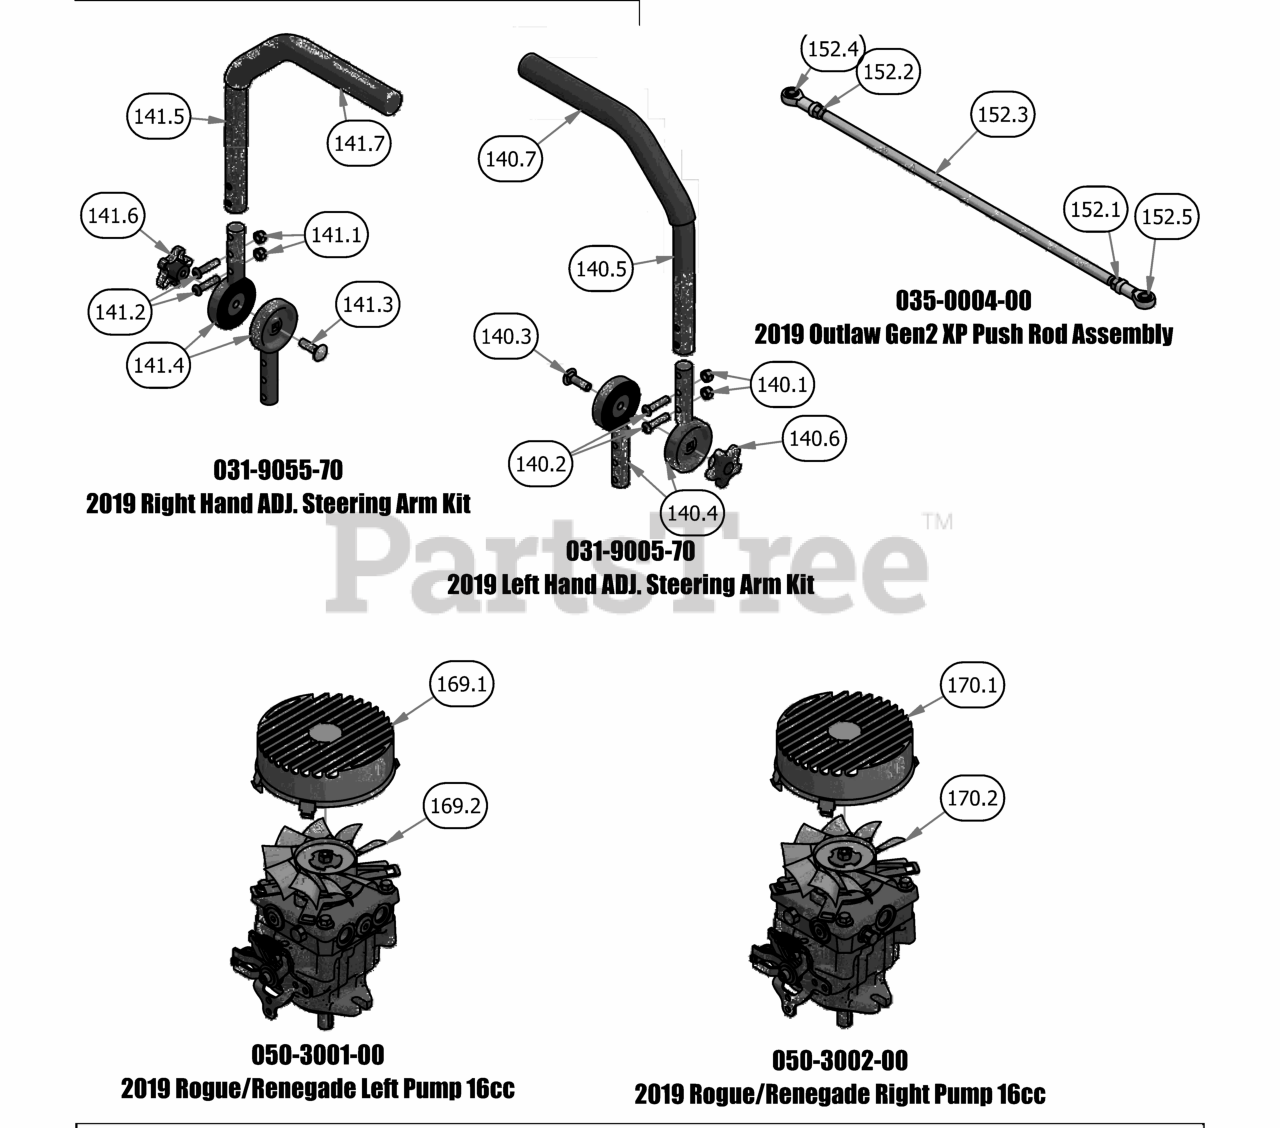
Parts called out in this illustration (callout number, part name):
140.1	5/16-18 Nylock Insert Locknut
140.2	5/16-18 BHCS, TORX DRIVE
140.3	3/8" x 1 1/4" Carriage Bolt
140.4	2019 Steering Arm Adjuster Casting
140.5	2019 Steering Arm Grip
140.6	Black Knob for Adjustable Steering Arm
140.7	Black Steering Arm Grip
141.1	5/16-18 Nylock Insert Locknut
141.2	5/16-18 BHCS, TORX DRIVE
141.3	3/8" x 1 1/4" Carriage Bolt
141.4	2019 Steering Arm Adjuster Casting
141.5	2019 Steering Arm Grip
141.6	Black Knob for Adjustable Steering Arm
141.7	Black Steering Arm Grip
152.1	5/16" RH Fine Threaded Jam Nut
152.2	5/16" LH Fine Threaded Jam Nut
152.3	2019 Outlaw Gen2 Xp Rod
152.4	Spherical Rod End - Outlaw
152.5	Spherical Rod End - Outlaw
169.1	Fan Guard 6" Fits wheel Motor Pumps
169.2	Hydraulic Fan
170.1	Fan Guard 6" Fits wheel Motor Pumps
170.2	Hydraulic Fan
